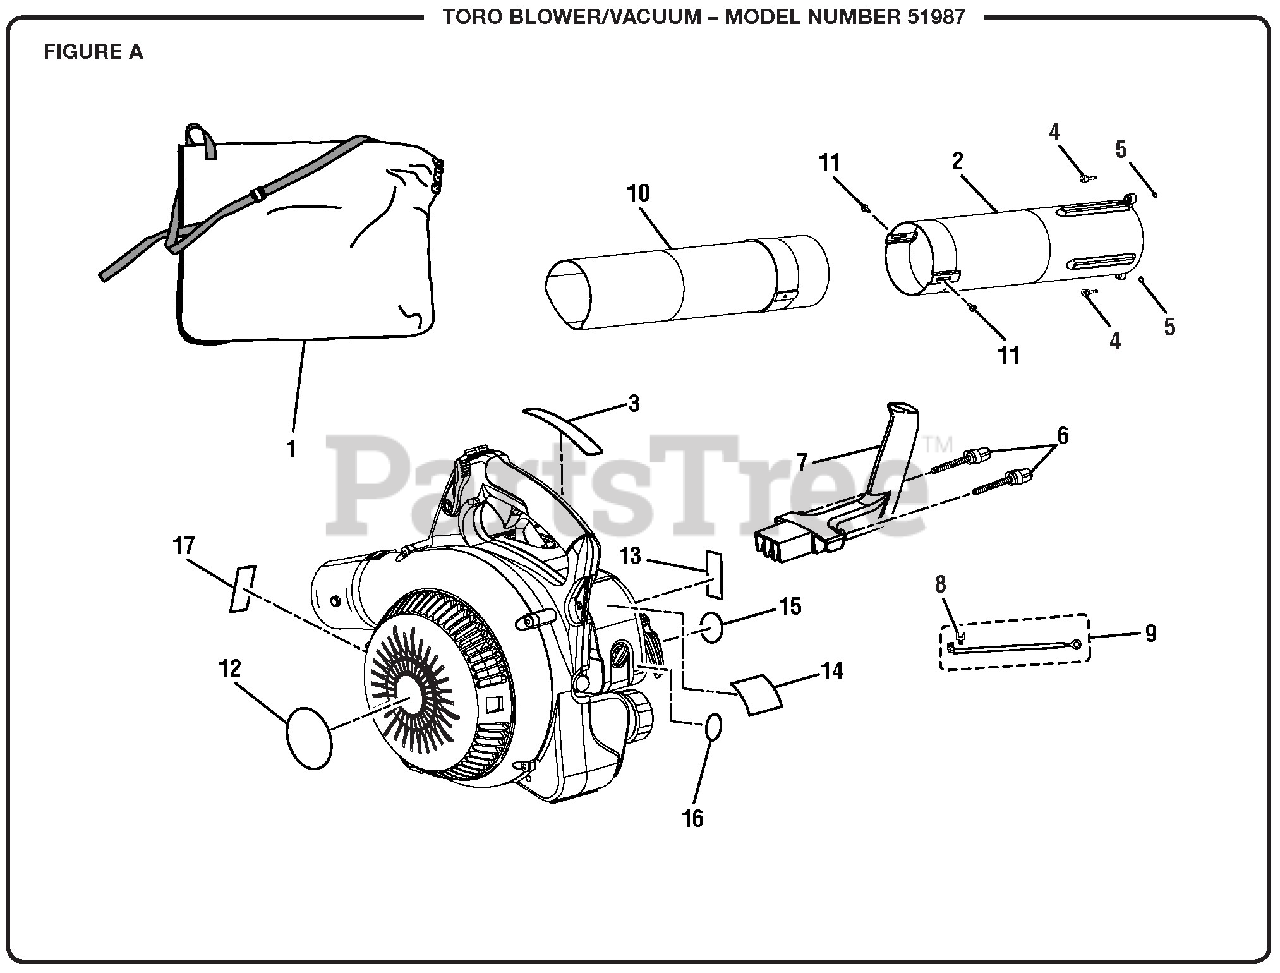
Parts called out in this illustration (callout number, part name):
1	Vacuum Bag w/Shoulder Strap
2	Upper Vacuum Tube
3	Icon Strip
4	Screw (1/4-20 x 3/4 in.)
6	Vacuum Handle Knob
7	Vacuum Handle
9	Ground Wire Kit
10	Lower Vacuum Tube
11	Vacuum Tube Screw (10-14 x 1/2 in.)
12	Vacuum Door Label
13	Choke Label
14	Starting Instructions Label
15	Starter Cover Label
16	Label, T25
17	Label, Combustion
